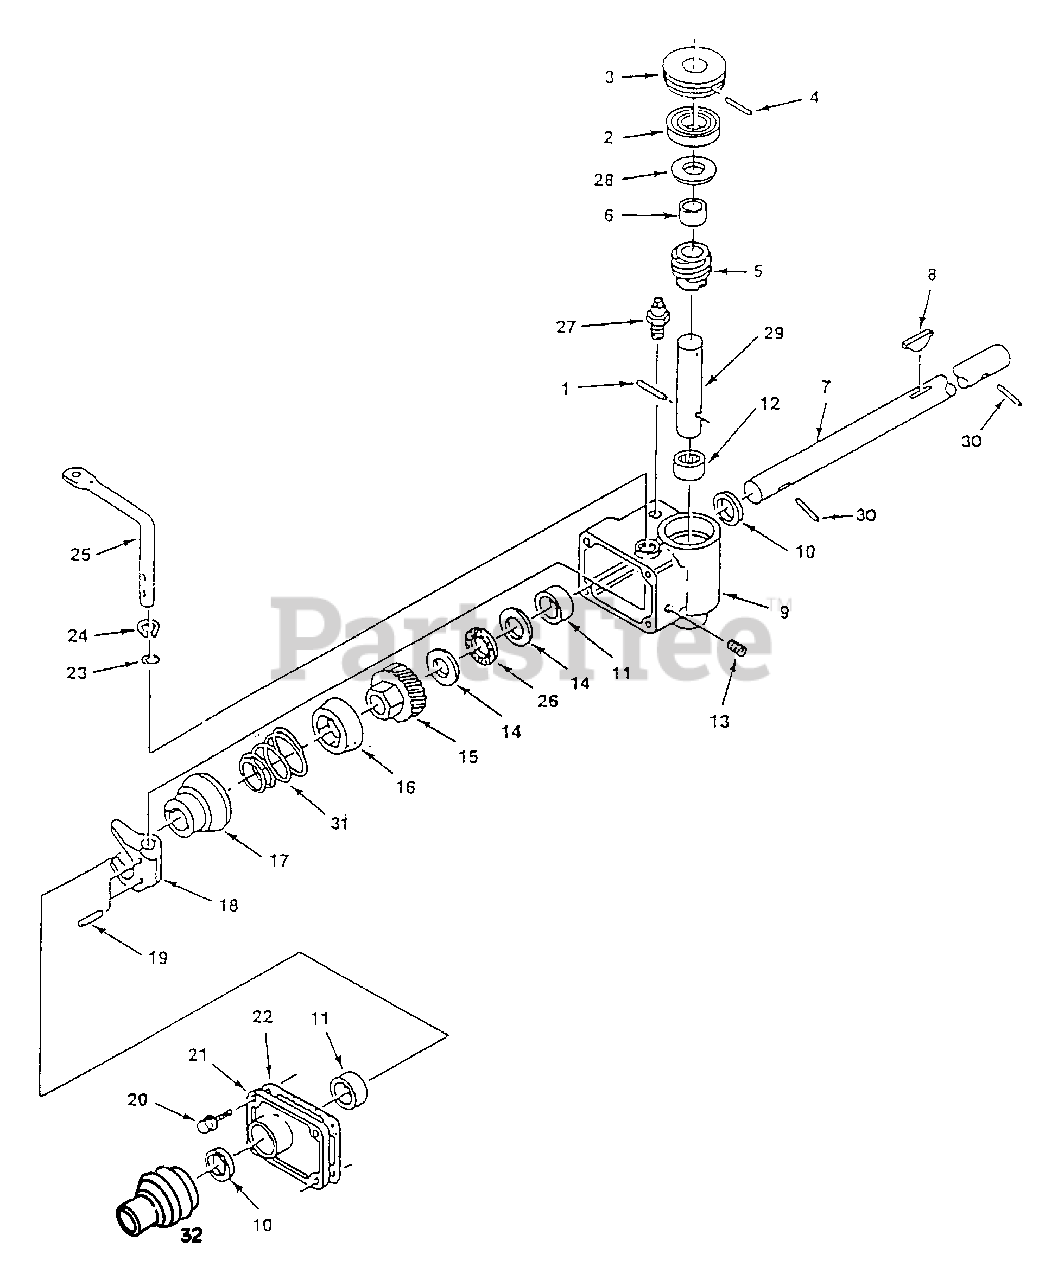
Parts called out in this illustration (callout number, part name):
1	Pin - roll 3/16 x 7/8
2	Bearing - bail
3	Pulley - drive
4	Pin - roll 3/32 x 1-1/4
5	Worm w/spacer
6	Spacer - worm
7	Shaft - drive
8	Key - Woodruff
9	Housing - gear
11	Bushing - sleeve
12	Bearing - needle
13	Plug - pipe
14	Race - thruston
15	Gear - helical
16	Cone - friction
17	Drum - clutch
18	Fork - shift
19	Pin - groove
20	Screw - hex 1/4-20 x 7/8 sems
21	Cover - gear box
22	Gasket - cover
24	Ring - retainer
25	Lever - shift
26	Bearing - needle
28	Washer - flat
29	Shaft-worm
30	Pin - roll 1/8 x 7/8
31	Spring - clutch
32	Shield - dust, plastic
